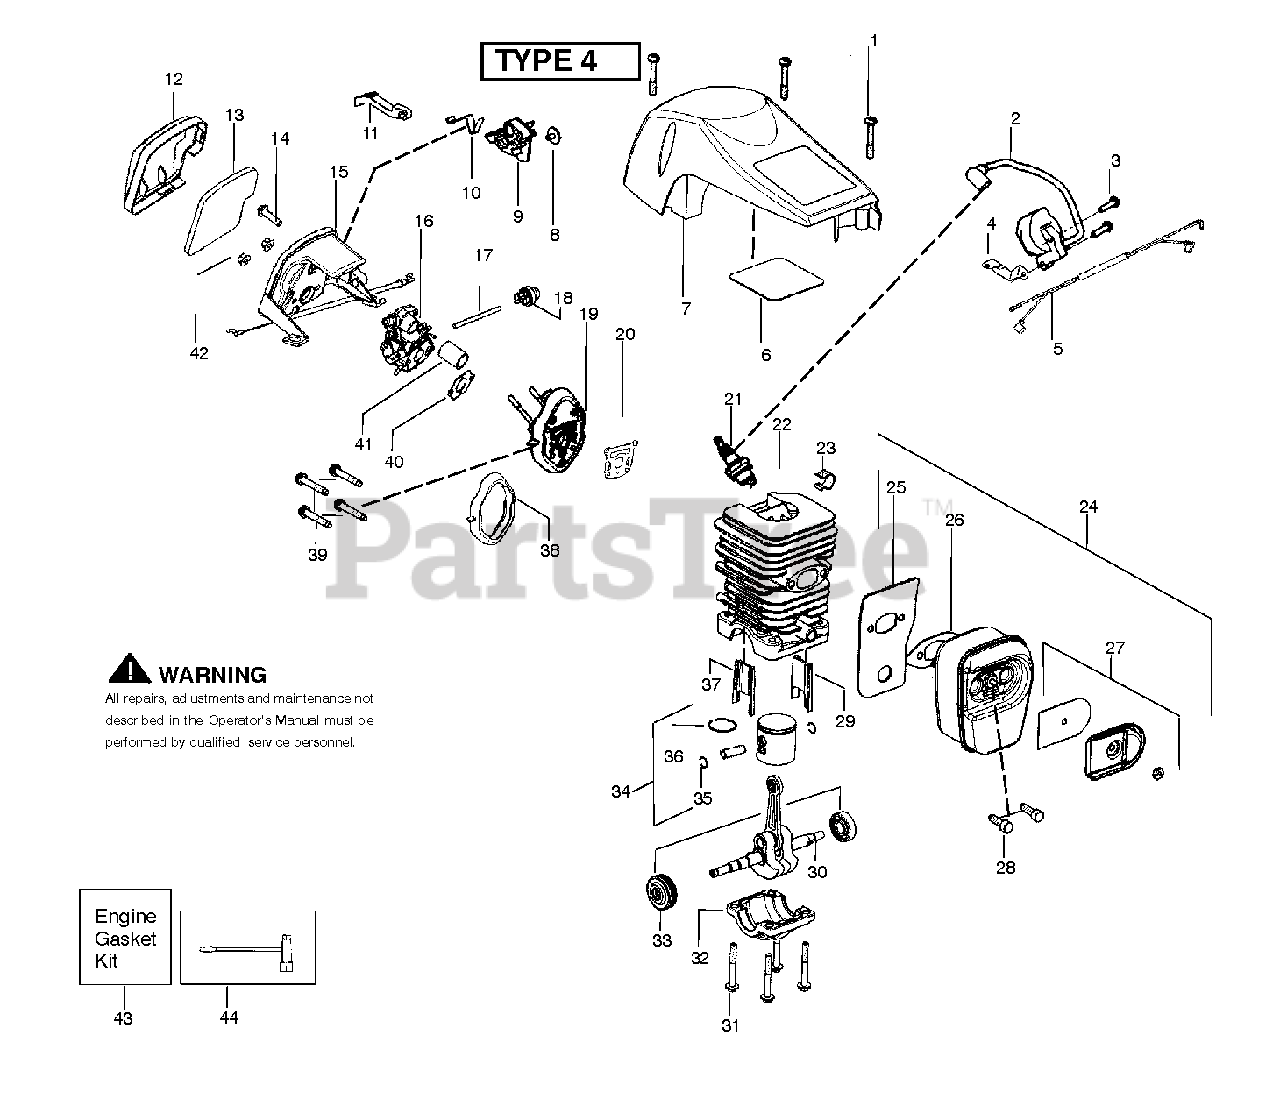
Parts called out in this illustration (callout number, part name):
2	MODULE IGNITION WALBRO
3	SCREW M5.38-14X22.225MM
4	STRAP GROUND
5	ASSY WIRE HARNESS
6	REFLECTOR-HEAT
7	HOUSING CYLINDER SHIELD
9	LEVER IGNITION SWITCH
10	SPRING IGNITION SWITCH
11	LEVER CHOKE
12	COVER AIR FILTER
13	FILTER AIR
14	SCREW M5-0.8X16
15	FILTER HSG & CABLE
16	CARB ZAMA W26B W/PURGE
17	KIT FUEL LINE
18	AIR PURGE
19	KIT CARB ADAPTOR
20	KIT GASKET SAS
21	SPARK PLUG (RCJ-7Y)
22	KIT CYLINDER
23	HIGH TENSION LEAD CLIP
24	KIT MUFFLER SAS NON CAT
25	PLATE BACK MUFFLER
26	KIT GASKET SAS
27	KIT SPARK ARRESTOR SAS NCAT
28	SCREW MUFFLER
29	INSERT TRANSFER LEFT
30	CRANKSHAFT & ROD ASSY
31	BOLT M6-1.0 X 25MM
32	CRANKCASE CASTING
33	BEARING & SEAL ASSEMBLY
34	KIT PISTON
35	C-CLIP,PSTN PIN 36/41
36	RING-PISTON
37	INSERT TRANSFER RIGHT
38	KIT GASKET SAS
39	SCREW M5-0.8X30MM
40	KIT GASKET SAS
41	TUBE INTAKE
43	KIT GASKET SAS
44	SCRENCH
